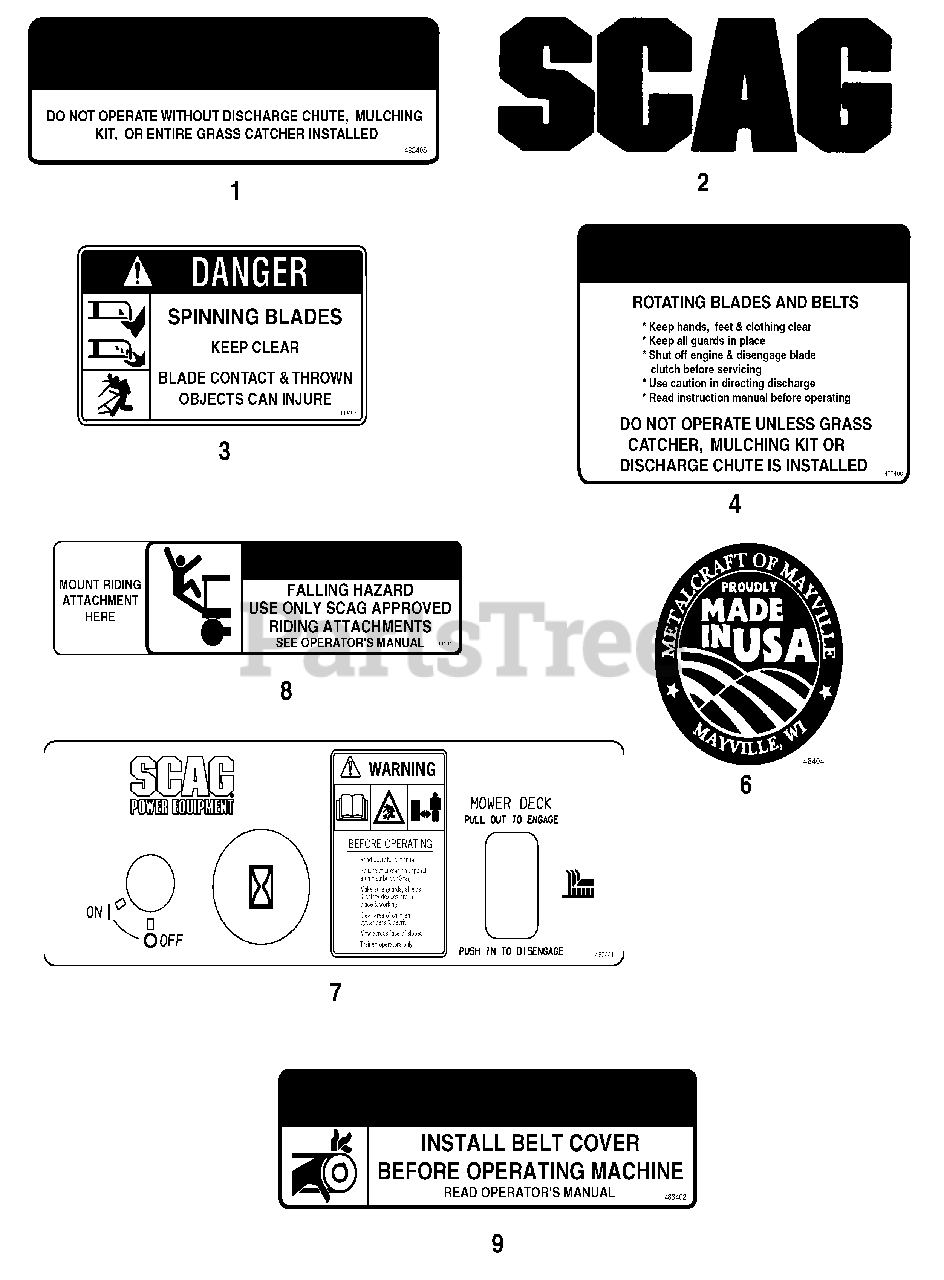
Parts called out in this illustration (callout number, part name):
1	Decal, Discharge Chute
2	Decal, Scag Logo
3	Decal, Danger-Spinning Blades
4	Decal, Warning-Rotating Blades
6	Decal, Metalcraft - Made in USA
7	Decal, Instrument Panel - Rear
8	Decal, Sulky Attachment
9	Decal, Belt Cover
